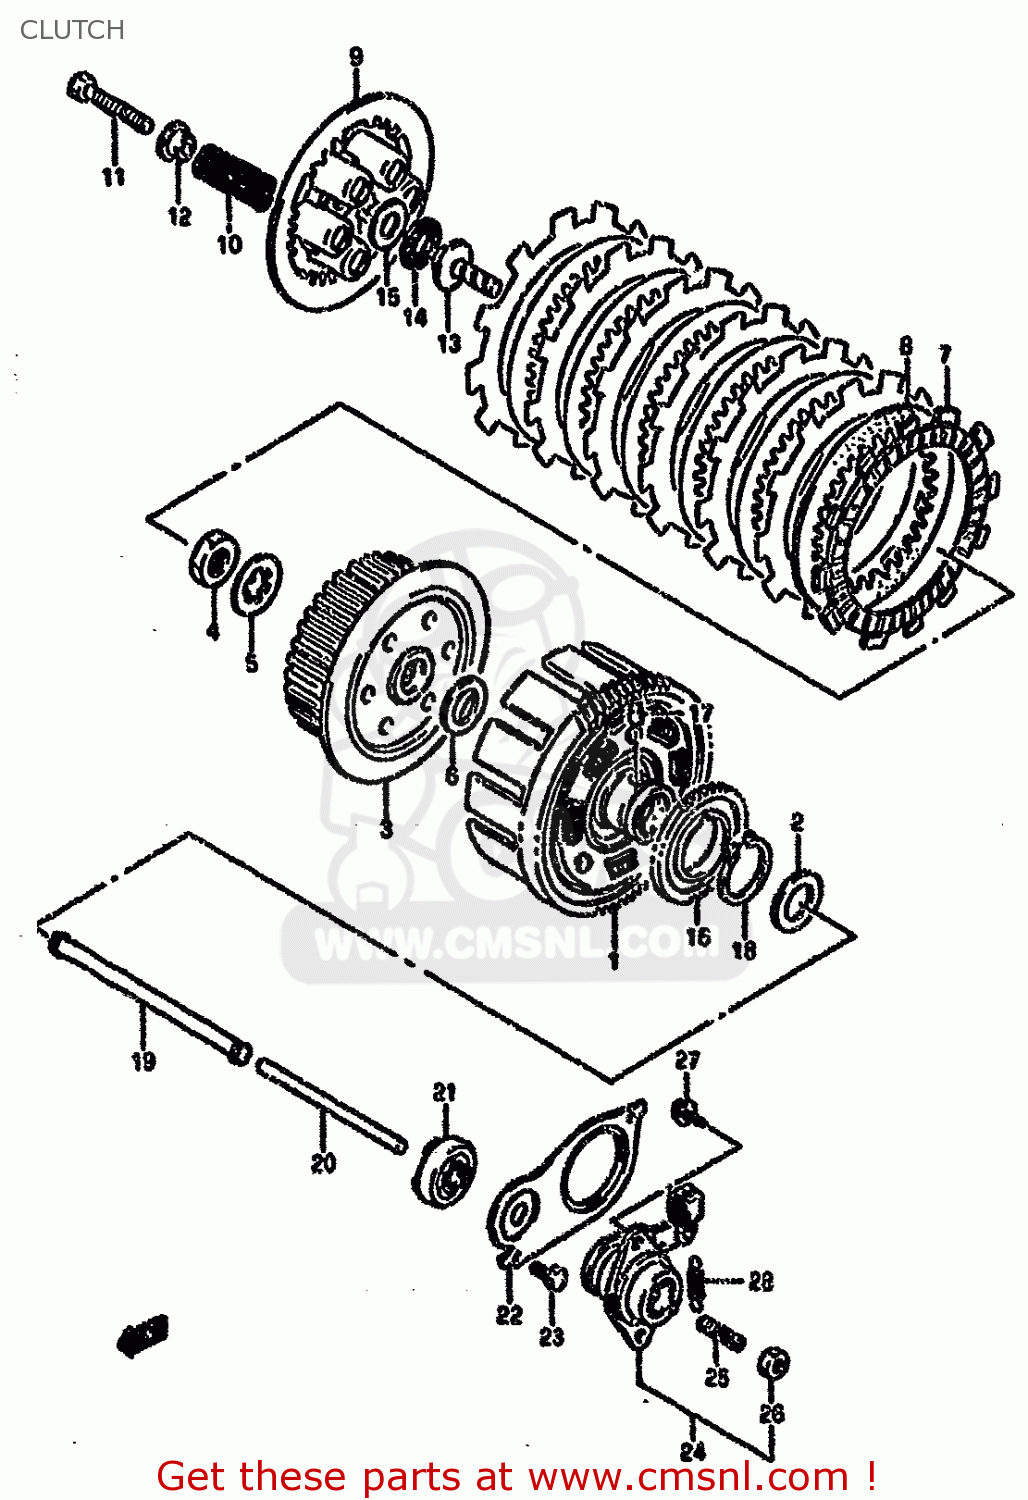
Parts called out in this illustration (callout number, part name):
1	GEAR ASSY,PRI DRIVEN
2	WASHER
3	HUB,CLUTCH SLEEVE
4	NUT (20MM)
5	WASHER,LOCK
6	WASHER(20X44X3)
7	PLATE,CLUTCH DRIVE (NAS)
8	PLATE,CLUTCH DRIVEN (NAS)
9	DISC,CLUTCH PRESSURE
10	SPRING
11	BOLT(6X40)
12	SPACER,CLUTCH SLEEVE HUB
13	PIECE,CLUTCH PUSH
14	BEARING(15X28X2)
15	WASHER
16	GEAR,OIL PUMP DRIVE
17	PIN(6X6)
18	CIRCLIP
19	ROD,PUSH,R
20	ROD,CLUTCH PUSH,L
21	SEAL,OIL(6X34X10)
22	RETAINER,PUSH ROD OIL SEAL
23	BOLT
24	SCREW ASSY,CLUTCH RELEASE
25	SCREW(6X25)
26	NUT
27	SCREW
28	SPRING
